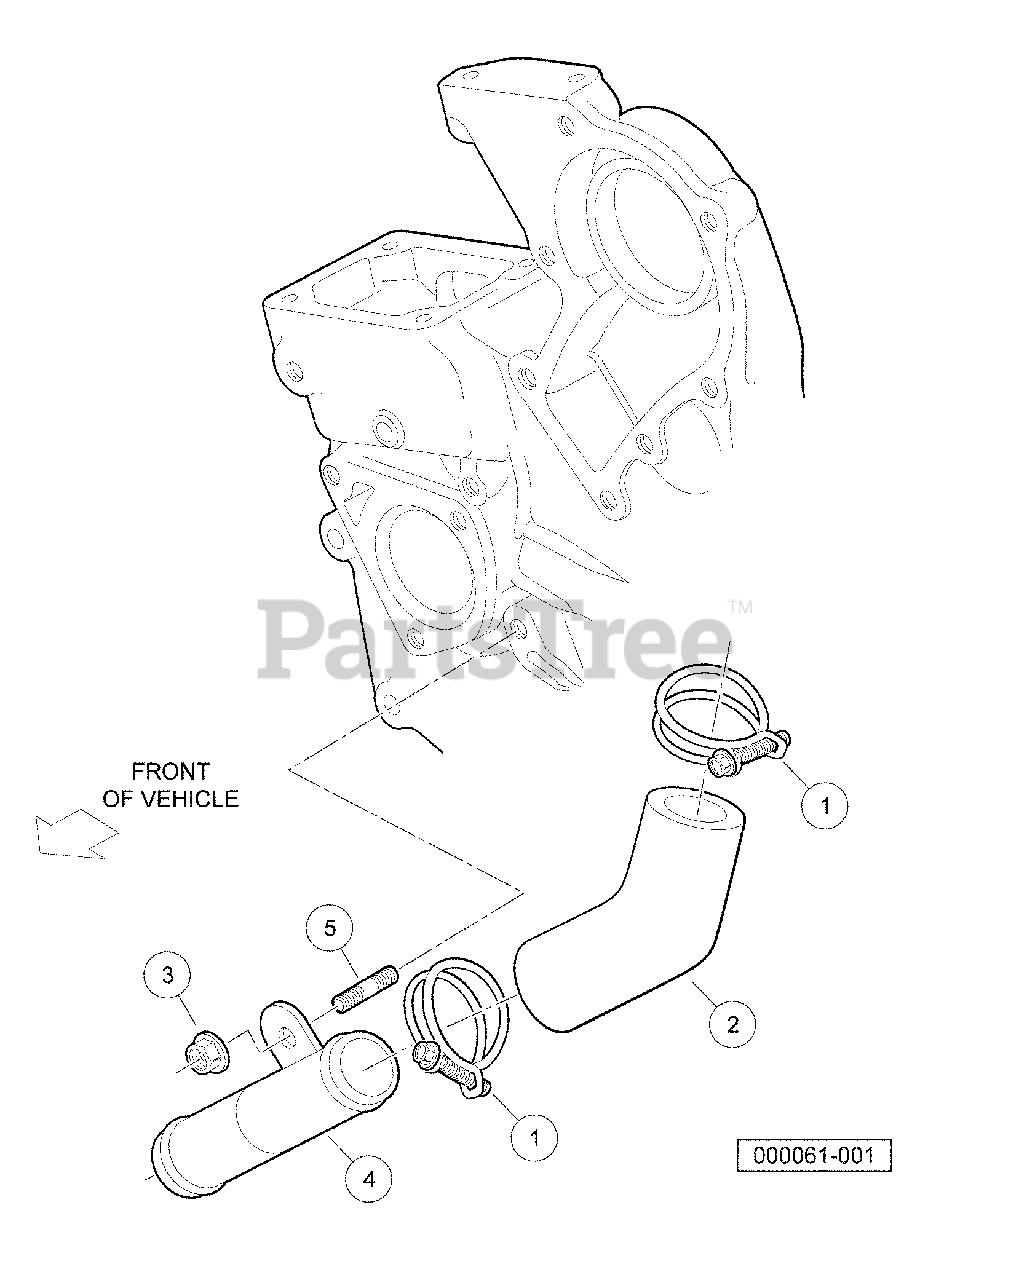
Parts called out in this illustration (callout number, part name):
1	Band, Pipe, with Nut
2	Pipe, Water, Bent
3	Nut, Flange, M6
4	Pipe, Water, Bent
5	Stud, M6 X 15
